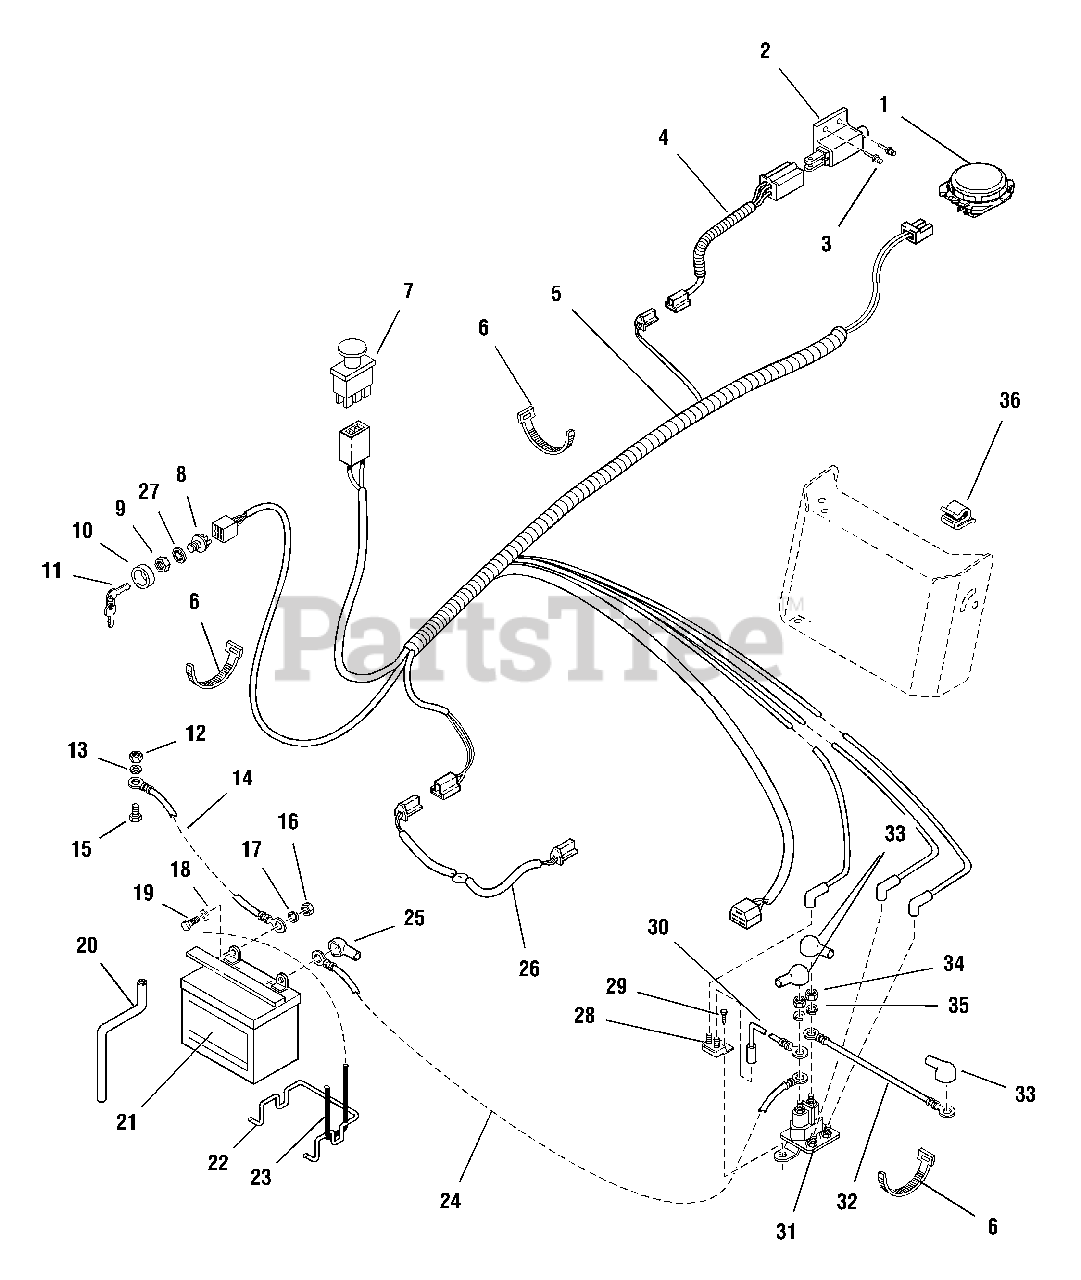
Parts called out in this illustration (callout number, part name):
1	SWITCH, Seat
2	SWITCH, Neutral Start
4	WIRE ASSEMBLY, Ground
5	HARNESS, Wiring
6	TIE, Self-Locking
7	SWITCH, PTO, Electric Clutch
8	SWITCH, Ignition (6 pole)
9	NUT, Hex
10	COVER, Keyswitch
11	KEYS (Set of 2 Keys)
12	NUT, Hex Flange Whiz Lock, 3/8-16
13	WASHER, Lock, External Tooth, 3/8
14	CABLE, Battery Ground
15	CAPSCREW, Hex Head, 3/8-16 x 5/8
16	NUT, Hex, 1/4-20
17	WASHER, Lock, 1/4
18	WASHER
19	CAPSCREW, Hex Head, 1/4-20 x 3/4
22	BRACE, Battery
23	STRAP, Battery
24	CABLE, Battery to Solenoid
25	BOOT, Insulator
26	WIRE ASSEMBLY, Clutch
27	WASHER, Internal Tooth, 5/8
28	CIRCUIT BREAKER
29	CAPSCREW, Hex Washer Head, Taptite, 1/4-20 x 1/2
30	WIRE ASSEMBLY
31	SOLENOID
32	CABLE, Solenoid to Starter
33	COVER, Terminal
34	NUT, Hex, 5/16-24
35	WASHER, Lock, 5/16
